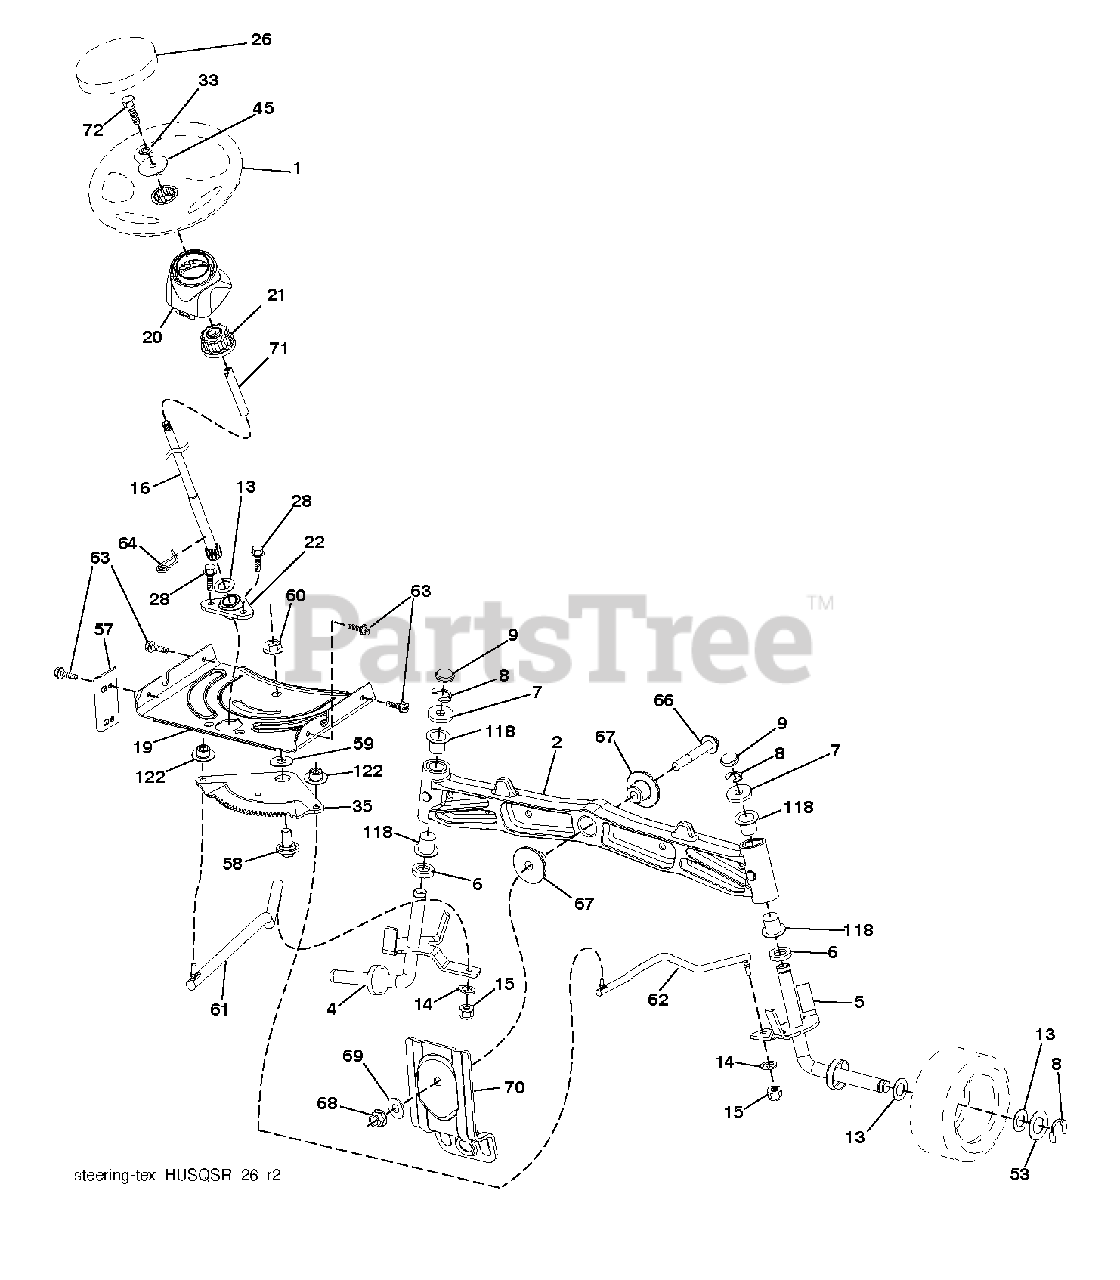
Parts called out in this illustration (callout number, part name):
1	WHEEL.STEERING.PREM.2.BLK
2	AXLE.SVC.ASM CAST IRON.TEX
4	SPINDLE.WELDED.LH.15"TEX
5	SPINDLE.WELDED.RH.15"T
8	RING CLIP
9	CAP.SPINDLE
14	WASHER, LOCK 3/8
15	NUT CROWNLOCK 3/8-24
16	SHAFT.STEER.3/4.PLATED.TEX
19	PLATE.STEER.DDL.NLT/NG
20	BOOT.STEERING.PREDATOR.LT.BLAC
21	ADAPTER, WHEEL STNG..
22	STEERING.SUPT.LOWER.
26	INSERT.CAP.STRG.WH.BLACK
28	SCREW, 3/8-16X3/4
33	LOCKWASHER
35	GEAR.SECTOR.PLATE.DDL.
45	WASHER.11/32
53	WASHER.HARDENED
57	BRACKET.UPSTOP.TEX
58	BOLT.SHOULDER.SECTOR.P
59	WASHER.THURST.SECTOR.S
60	NUT FLANGE LOCK 5/8-11
61	DRAGLINK.LH.BALLSTUD.D
62	DRAGLINK.RH.BALLSTUD.D
63	SCREW
64	RETAINER.CLIP.SPRING.S
66	BOLT HEX FGHD 7/16-14 X 3 SERR
67	BUSHING.PM.FRONT AXLE
68	NUT.LOCK.FLANGE.7/16
69	WASHER.1.5X.505X.118
70	BRKT.DECK.SUSPENSION.F
71	SHAFT.EXTEN.STRG.SPLINE
72	BOLT 5/16-18 X 4 W/PATCH
118	BUSHING, AXLE CAST
